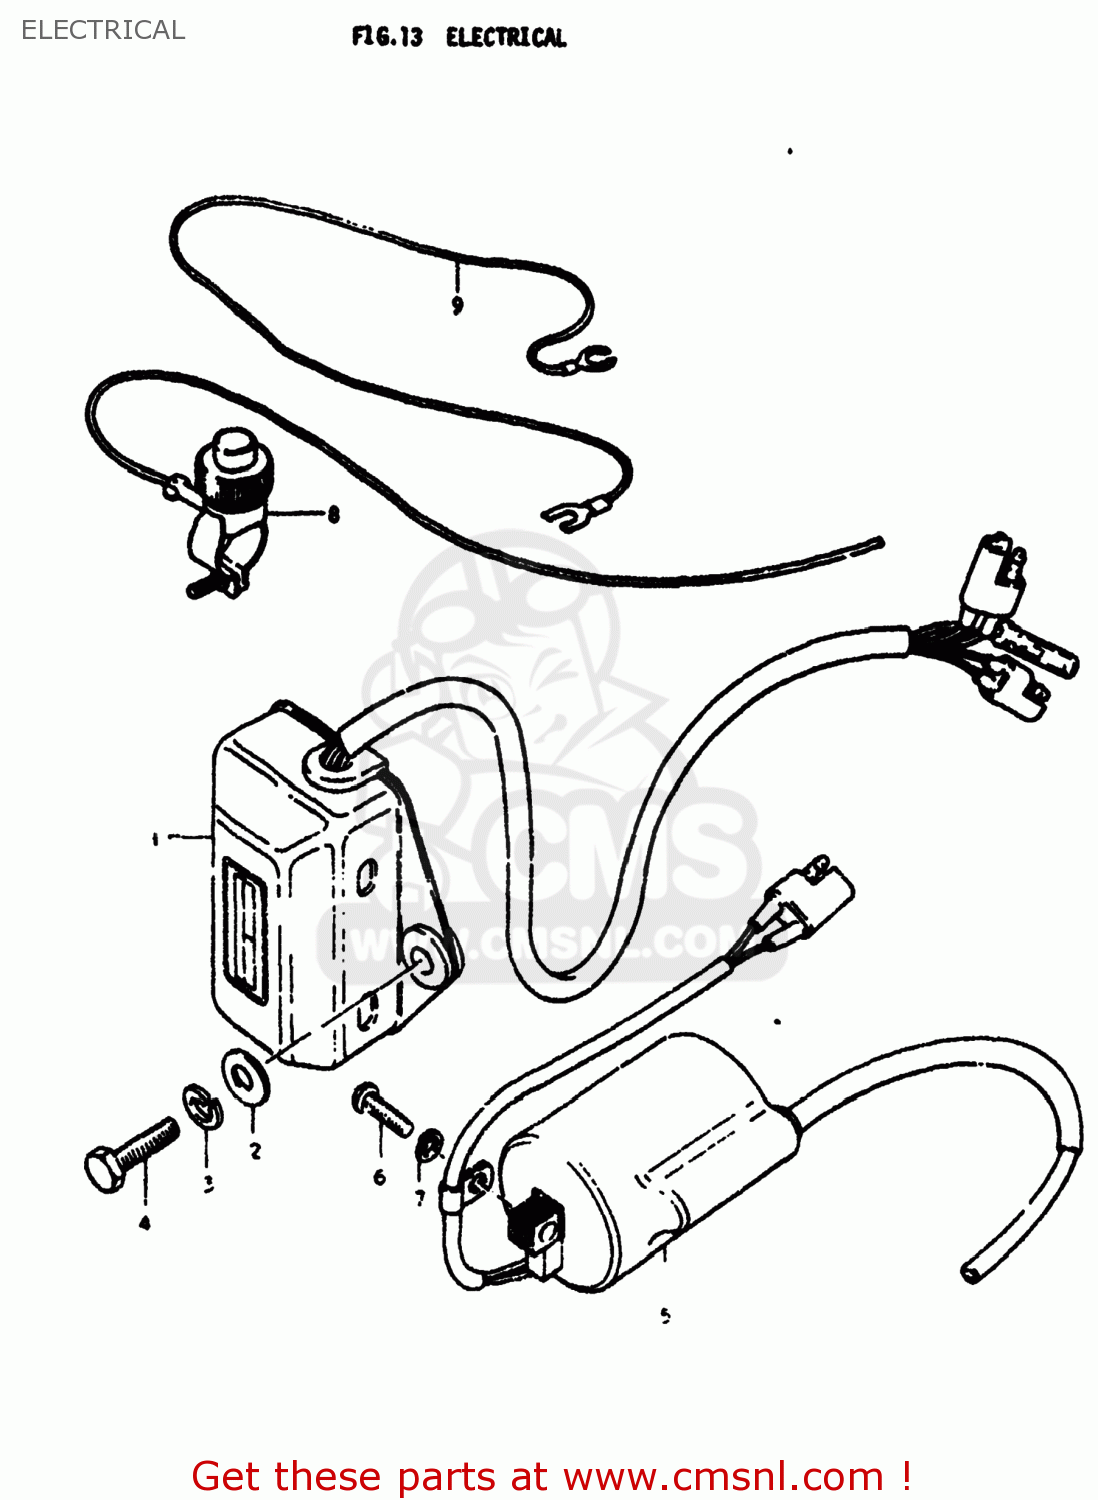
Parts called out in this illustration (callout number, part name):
1	CDI UNIT ASSEMBLY
2	WASHER(6.5X16X1.2)
3	LOCK WASHER
4	BOLT
5	COIL ASSY,IGNITION
6	SCREW 5X20
7	LOCK WASHER
8	SWITCH ASSEMBLY
9	WIRE,ENGINE STOP EARTH
